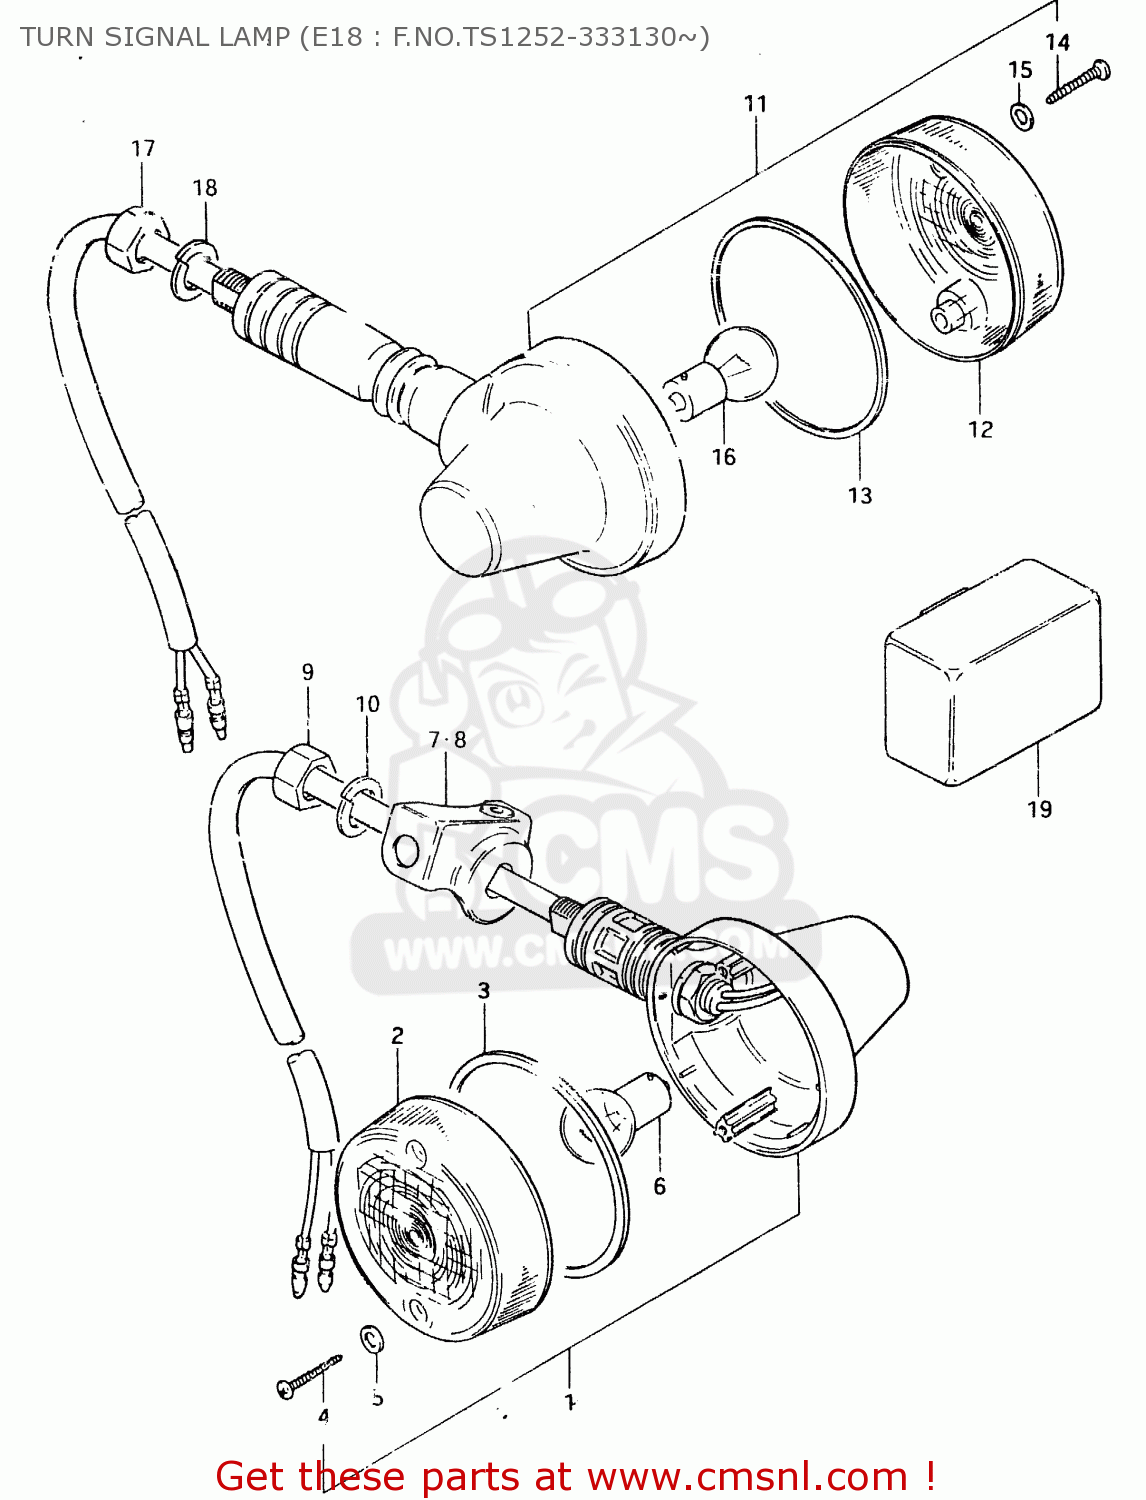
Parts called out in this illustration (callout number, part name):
1	LAMP, FRONT TURN SIGANL
2	LENS
3	GASKET (NAS)
4	SCREW
5	GASKET (NAS)
6	BULB (6V,21W)
7	BRACKET,TURNSIGNAL LAMP,R
8	BRACKET,TURNSIGNAL LAMP,L
9	NUT
10	WASHER,LOCK 12
11	LAMP, REAR TURN SIGNAL
12	LENS
13	GASKET (NAS)
14	SCREW
15	GASKET (NAS)
16	BULB (6V,21W)
17	NUT
18	LOCK WASHER
19	RELAY, TURN SIGNAL
